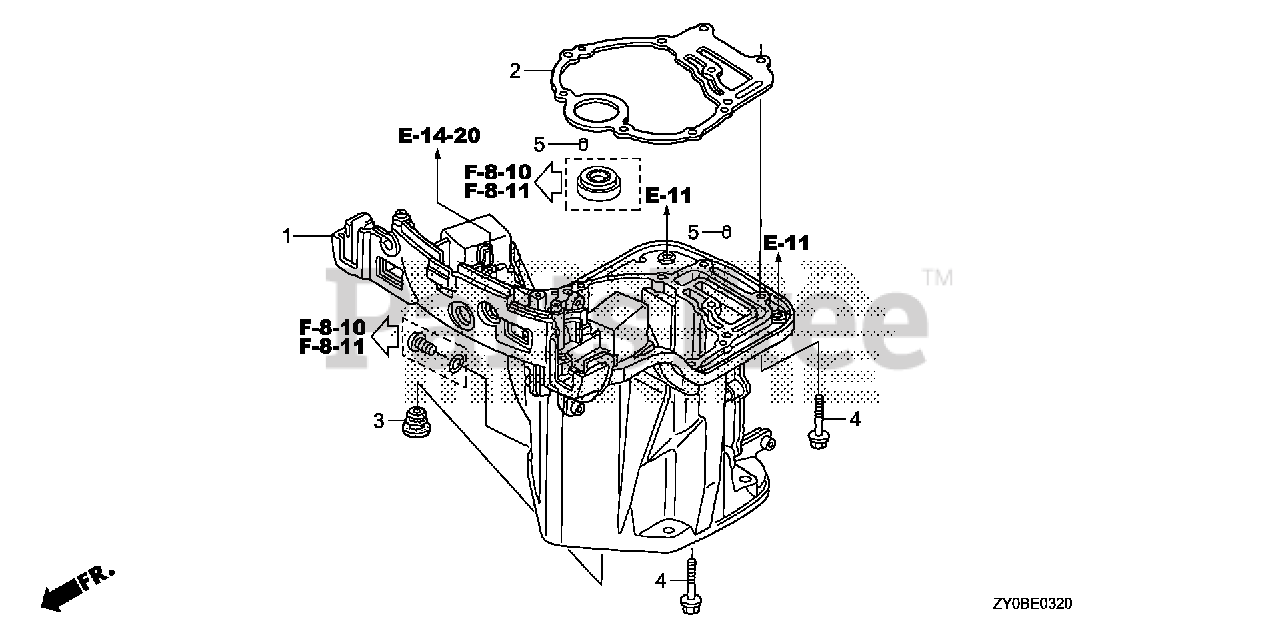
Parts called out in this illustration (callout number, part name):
1	CASE, OIL *NH282MU* (OYSTER SILVER METALLIC-U)
2	GASKET, OIL PAN
3	GROMMET, WATER TUBE
4	BOLT, FLANGE (8X35)
5	PIN, DOWEL (6X10)
